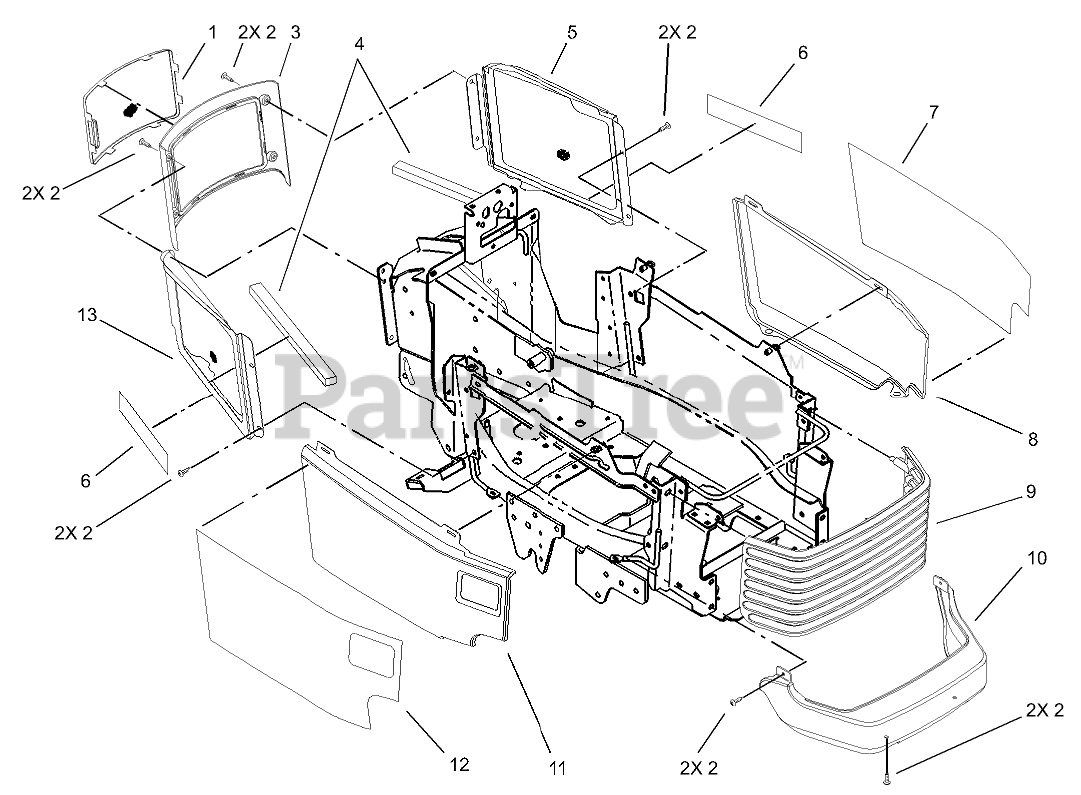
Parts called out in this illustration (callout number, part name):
1	SCREEN-REAR
2	SCREW-HH
3	COVER-REAR
4	FOAM-SEAL, SIDE SCREEN
5	Cover-Side LH
6	DECAL-523 DXI
7	Decal-Hood, LH
8	PANEL-SIDE, LH HOOD
9	GRILL
10	COVER-BUMPER
11	PANEL-SIDE, RH HOOD
12	Decal-Hood, RH
13	Cover-Side, RH
